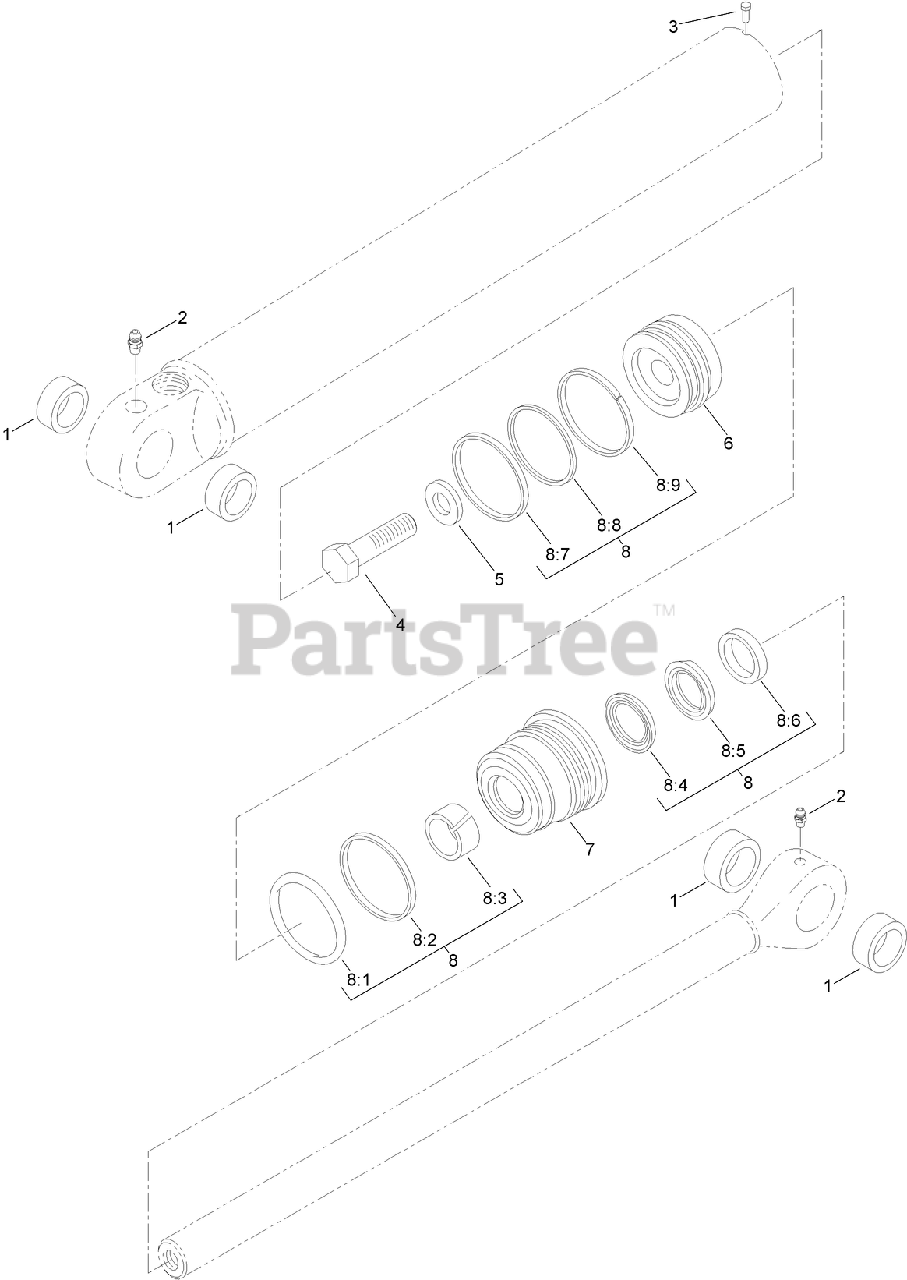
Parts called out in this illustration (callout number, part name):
1	BUSHING
2	FITTING-GREASE
5	WASHER
8	SEAL KIT
8:2	RING-BACKUP
8:3	BEARING-ROD
8:4	SEAL-BUFFER
8:5	SEAL-ROD
8:6	WIPER-ROD
8:7	SEAL-Piston
8:8	RING-LOADER
8:9	RING-WEAR
